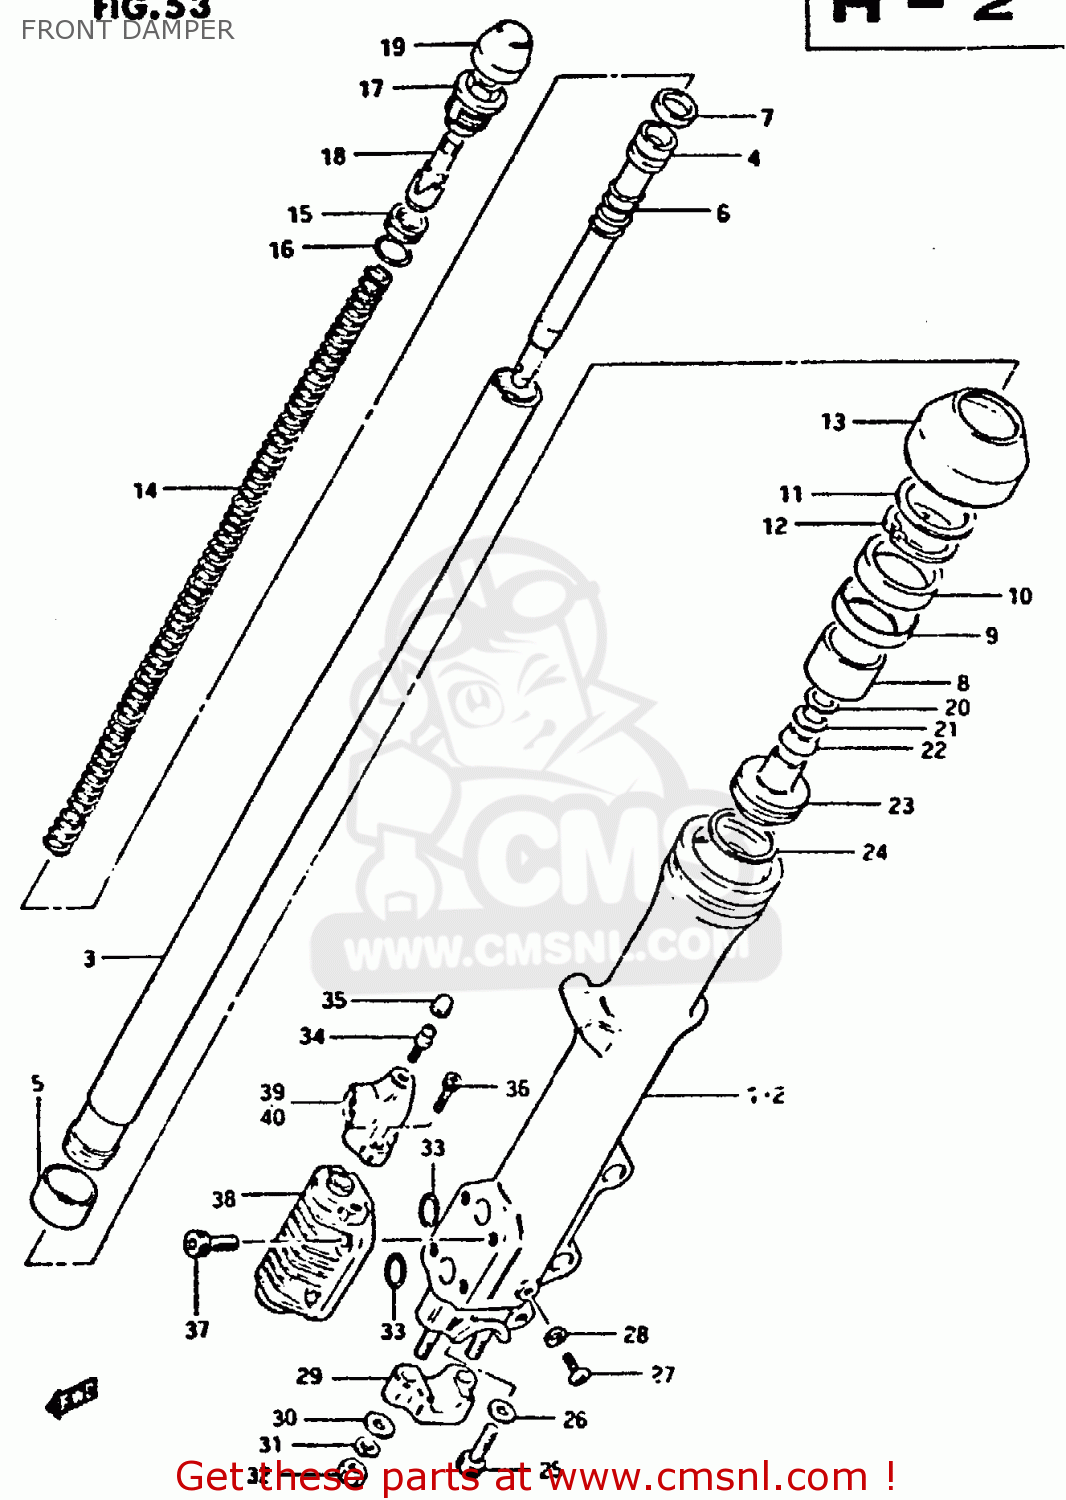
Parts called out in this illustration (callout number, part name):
1	TUBE,OUTER,RIGHT
2	TUBE,FORK,LEFT,OUTER
3	TUBE,FORK,INNER
4	CYLINDER,FRONT FORK
5	PISTON
6	SPRING REBOUND
7	RING,PISTON
8	GUIDE,FORK INNER TUBE
9	SPACER,SEAL
10	OIL SEAL,FRONT FORK
11	RING,BACKUP
12	CIRCLIP,INNTERNAL
13	BOOT
14	SPRING,FRONT
15	SEAT,FRONT FORK SPRING
16	O RING
17	CAP,FORK INNER TUBE
18	ADJUSTER,SPRING
19	CAP
20	VALVE
21	SPRING,VALVE
22	VALVE,OIL LOCK PIEACE
23	PIECE,OIL LOCK
24	RING,PISTON
25	BOLT(8X27)
26	GASKET (NAS)
27	SCREW 4X6
28	GASKET (NAS)
29	HOLDER,AXLE
30	WASHER
31	LOCK WASHER
32	NUT
33	O RING,FR FORK
34	BREATHER
35	CAP
36	BOLT
37	BOLT
38	MODULATOR PLANGER SET
39	MODULATOR PLANGER SET
40	MODULATOR PLANGER SET
